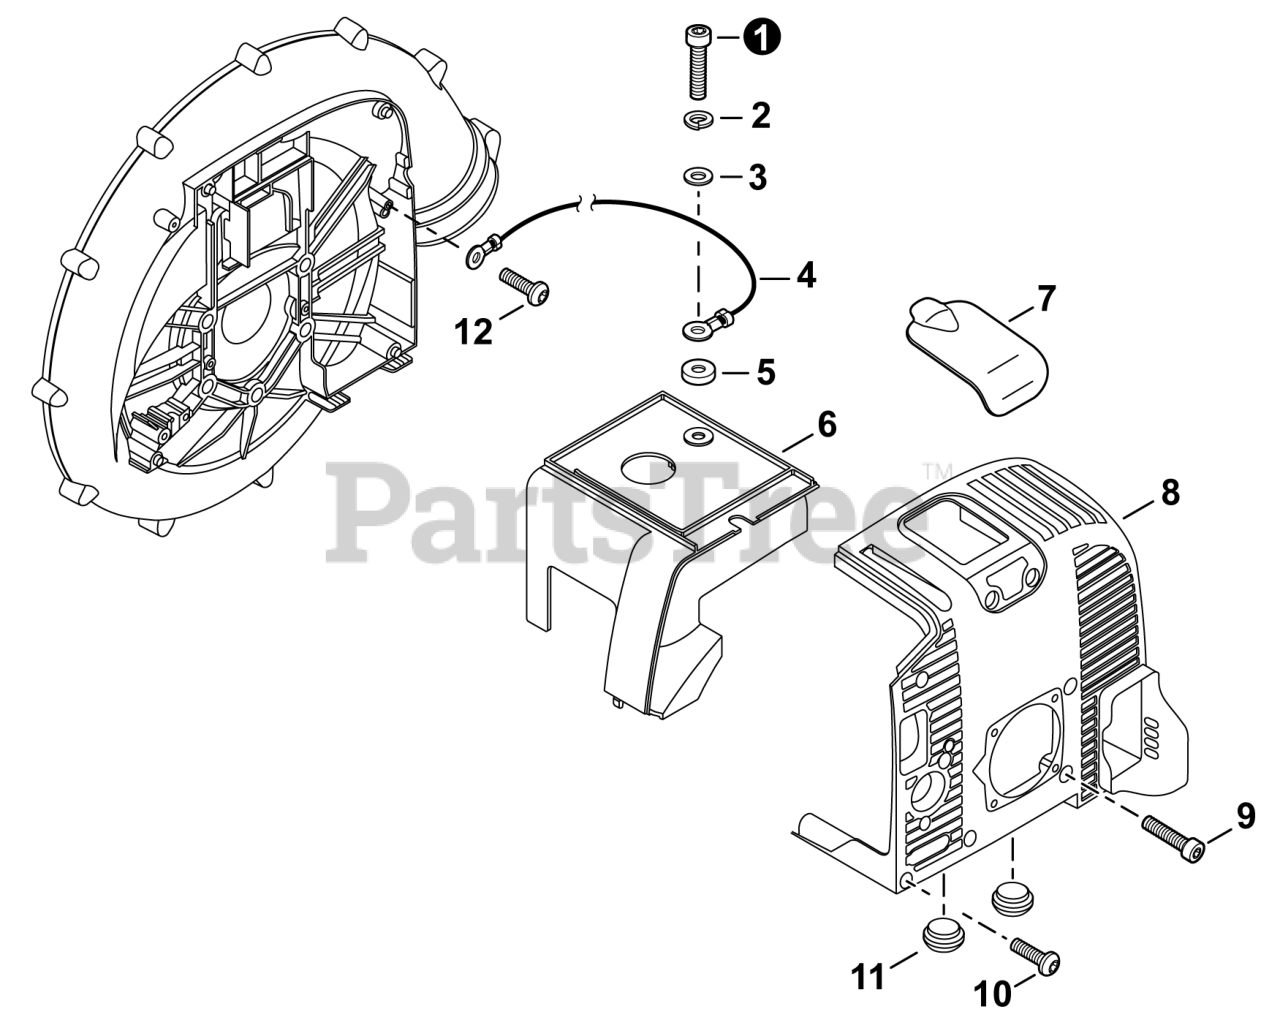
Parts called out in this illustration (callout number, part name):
1	BOLT 5×20
2	WASHER, SPRING 5
3	WASHER, FLAT 5.5×10×0.8
4	LEAD L= 295 MM
5	WASHER 5.2×14×T3
6	COVER, CYLINDER
7	COVER, SPARK PLUG
8	COVER, ENGINE
9	BOLT, TORX 5×16
10	BOLT, TORX 5×20
11	CUSHION
12	BOLT, TORX 5×12
